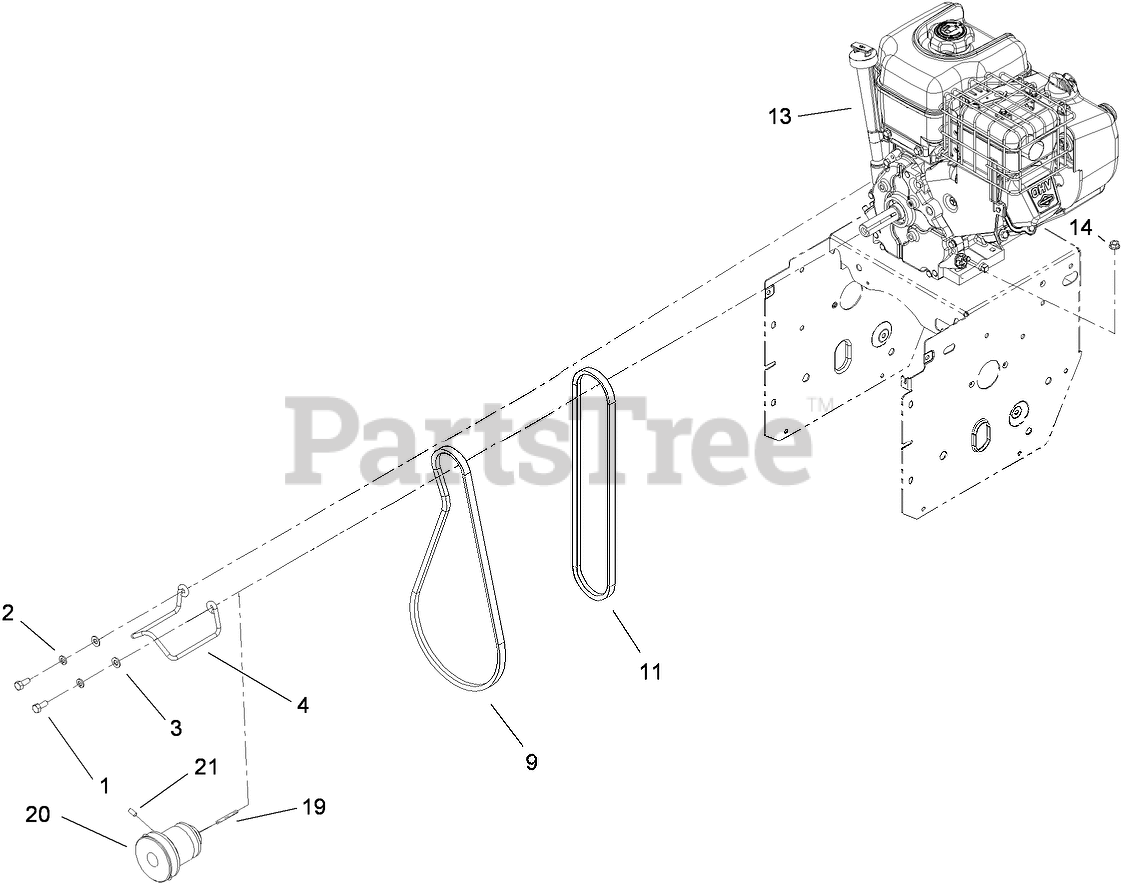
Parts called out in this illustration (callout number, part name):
1	SCREW-HH
2	WASHER-LOCK
3	WASHER-PLAIN
4	GUIDE-BELT
9	BELT-V
11	V BELT-TRACTION
13	ENGINE-BRIGGS 15D102-0111-E1 CE
14	NUT-HF
19	KEY-SQUARE
20	PULLEY-ENGINE
21	SCREW-SET, HSH
